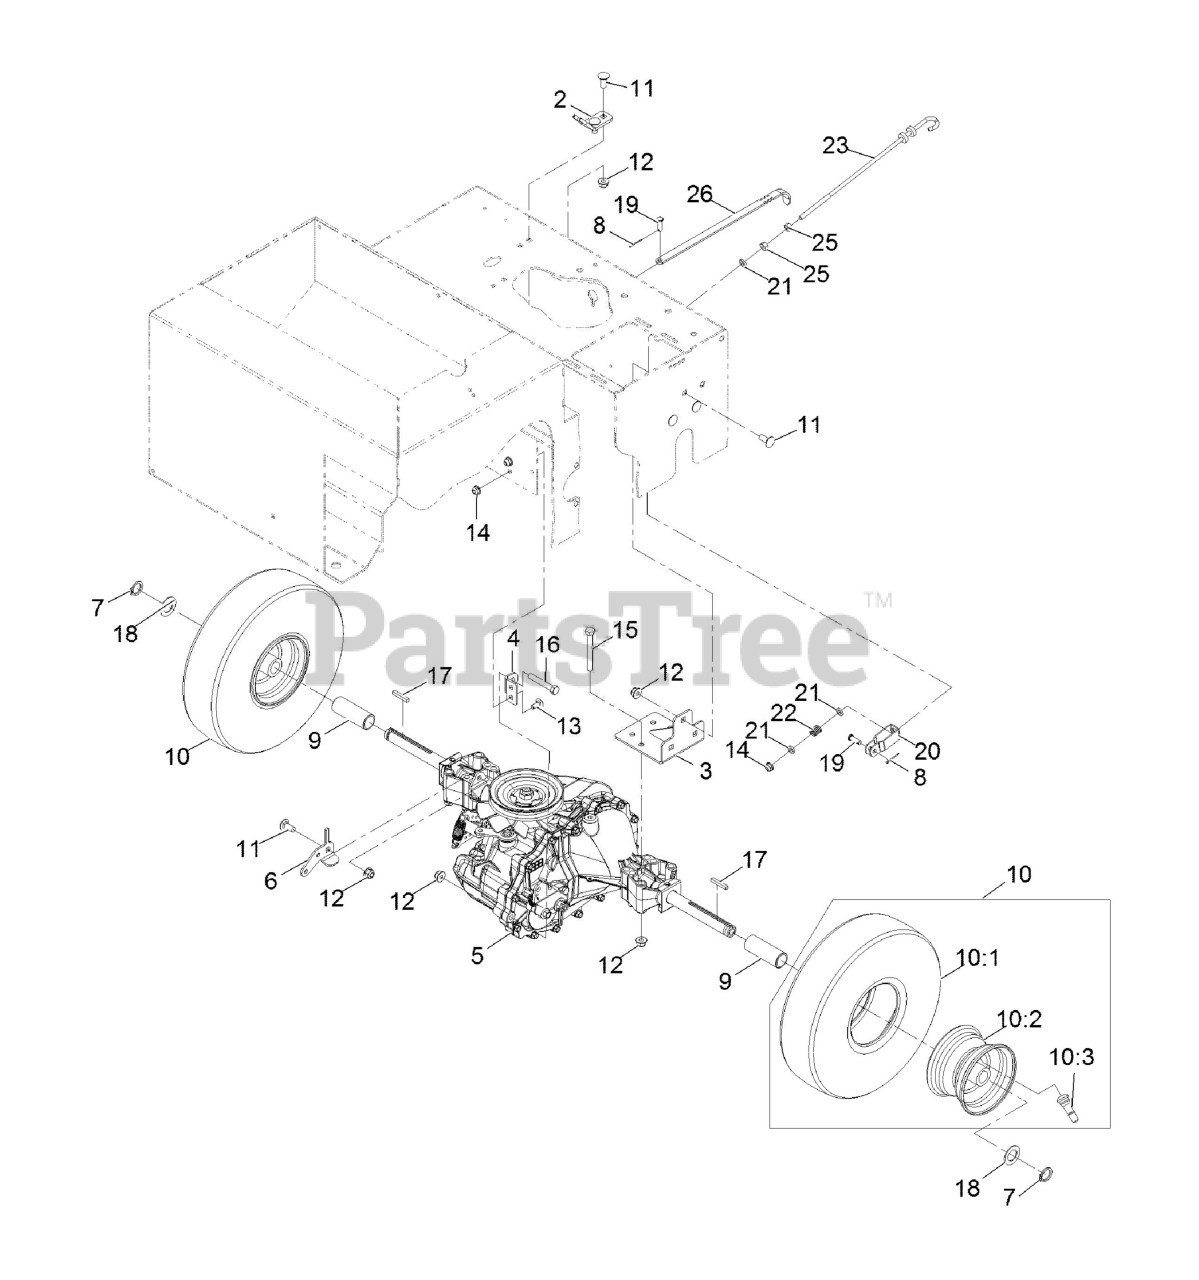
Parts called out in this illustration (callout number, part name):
2	BRACKET-CABLE
3	BRACKET-AXLE
4	BRACKET-TRANSAXLE, TORQUE
5	TRANSAXLE ASM
6	BRACKET-TRANSAXLE
7	RING-RETAINING
8	PIN-COTTER
10	WHEEL ASM
10:2	WHEEL-RIM
10:3	VALVE
11	SCREW-CARR
12	NUT-HF, NI
13	SCREW-CARR
15	SCREW-HH
16	SCREW-HH
17	KEY-SQUARE
19	PIN-CLEVIS
21	SPACER-PLATE, PIVOT
22	SPRING-COMPRESSION
23	ROD-BRAKE
25	NUT-HEX
26	LEVER-BYPASS
